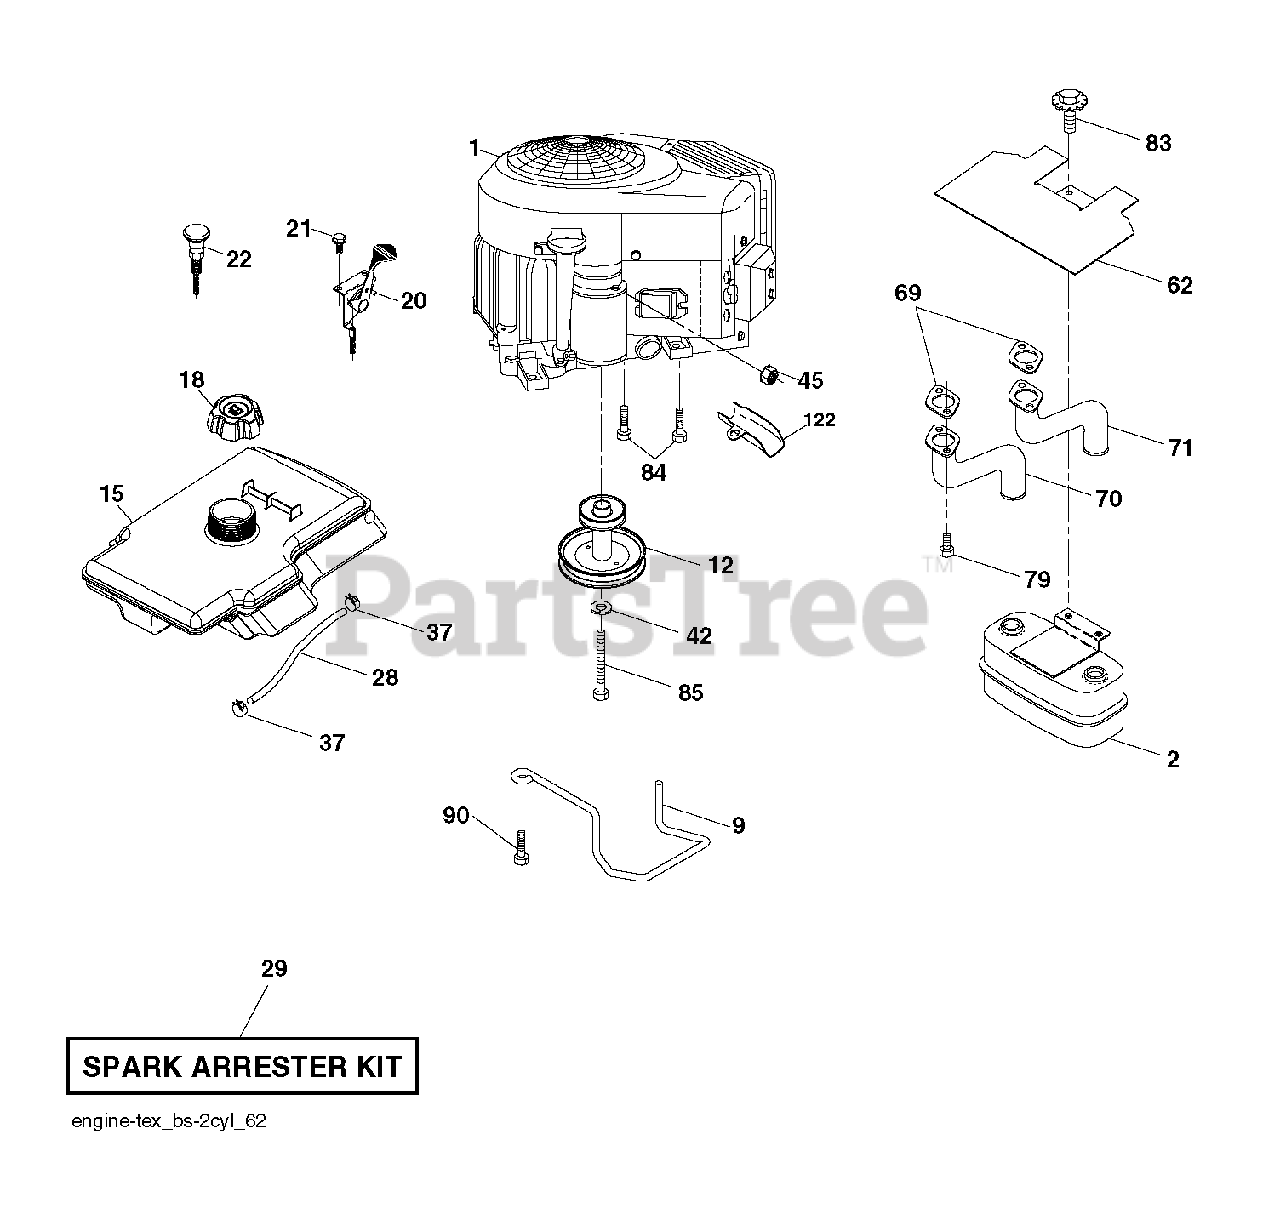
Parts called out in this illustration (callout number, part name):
2	MUFFLER.TWIN.CYL.LOW.TONE
9	KEEPER.BELT.ENGINE.4.2
12	PULLY ENGINE
18	CAP.ASM.FUEL.TANK.3"BLACK
20	THROTTLE CABLE
21	SCREW.#10 X 0.750.BOS THREAD
22	CONTROL CHOKE
29	ARRESTER SPARK (OPTIONAL)
37	HOSE CLAMP
42	LOCKWASHER
45	NUT
62	SHIELD.HEAT.MUFFLER
69	GASKET.MUFFLER
70	TUBE MANIFOLD LH
71	EXHAUST TUBE RH
79	SCREW.SOCKET.HEAD.5/16-18
83	BOLT, 5/16-18 X 1 3/4
84	SCREW.3/8-16
85	BOLT HEX 7/16-20X4-1/4"
90	SCREW 3/8-16X1
122	EXTENSION DRAIN OIL
